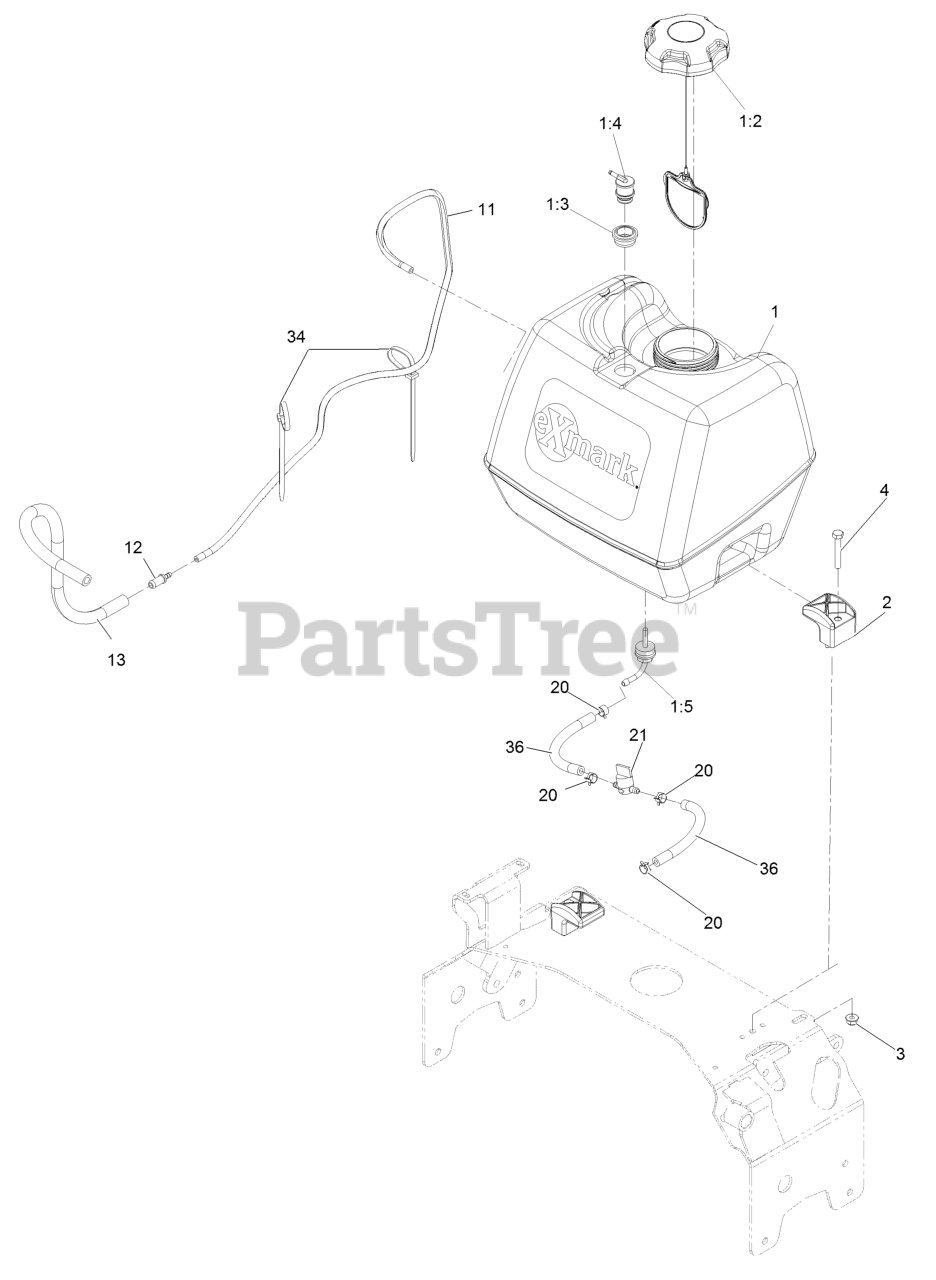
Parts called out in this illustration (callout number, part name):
1	ASM, FUEL TANK
1:3	GROMMET
1:4	VALVE-VENT, FUEL
1:5	FITTING-FUEL, BULKHEAD
3	NUT-HF, NI
4	SCREW-HH
11	HOSE, EMISSIONS
12	FITTING-STRAIGHT
13	HOSE-FUEL
20	CLAMP-HOSE
21	VALVE-FUEL
34	TIE-PLASTIC
36	HOSE-FUEL
